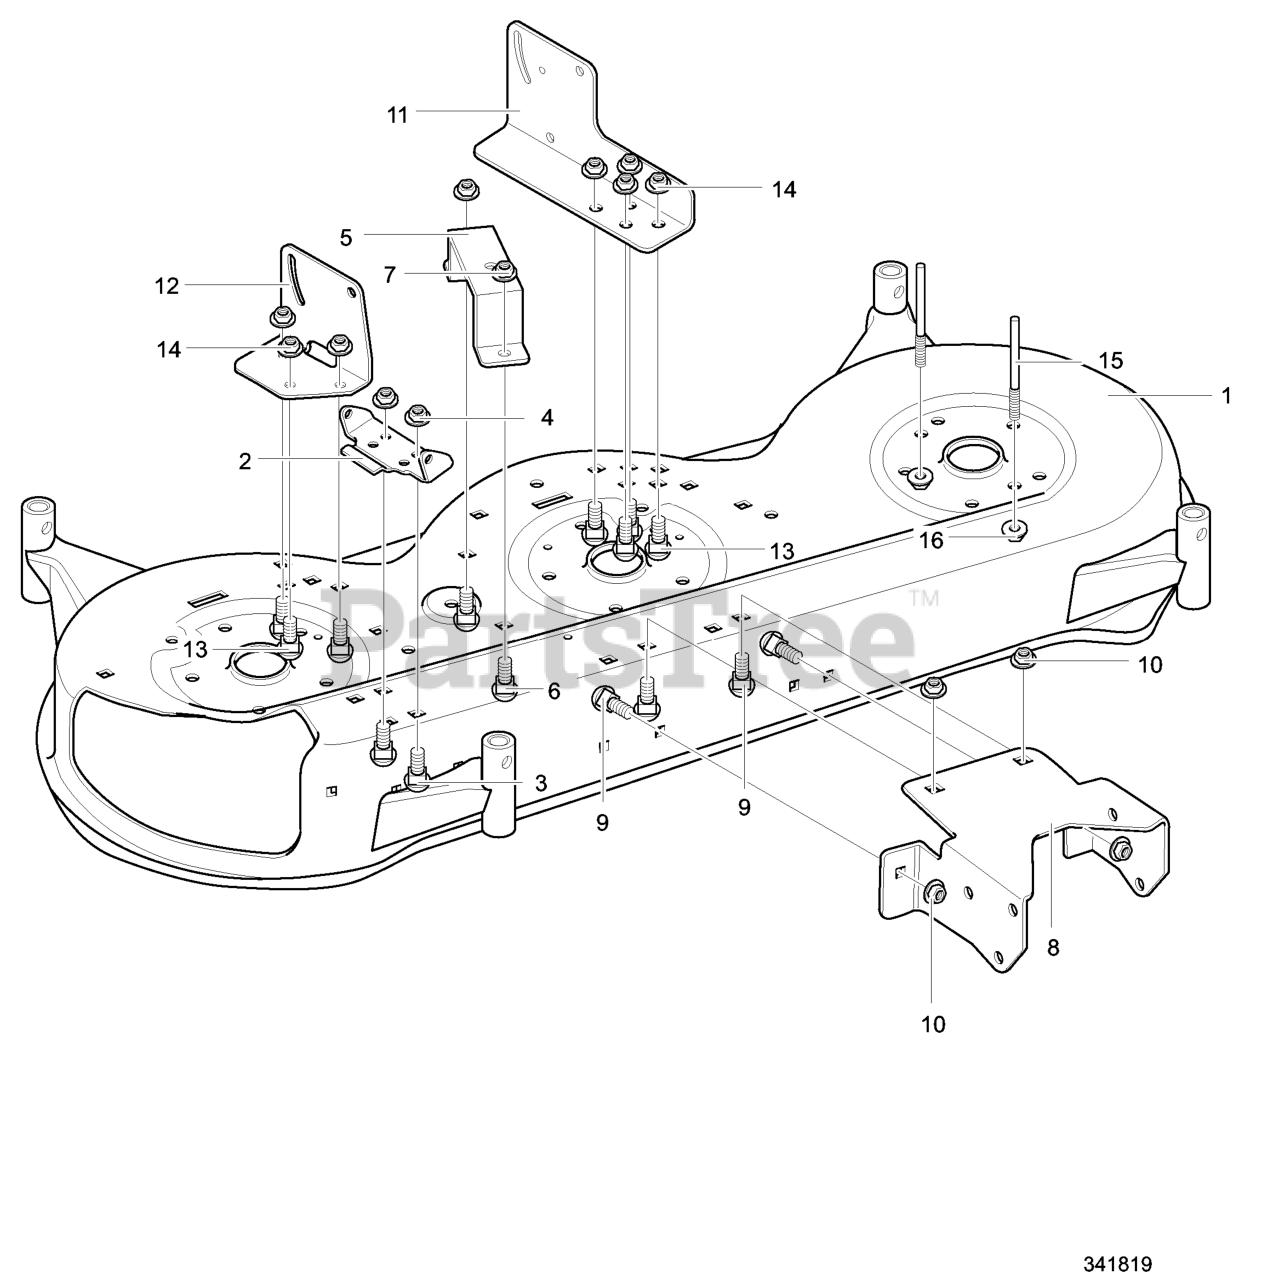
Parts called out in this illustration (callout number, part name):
1	MOWER DECK, 46"
2	HINGE, CHUTE BRACKET
3	BOLT, CARRIAGE
4	LOCKNUT, FLANGE
5	BRACKET, BELL CRANK
6	BOLT, CARRIAGE
7	LOCKNUT, FLANGE
8	BRACKET, FRONT DECK
9	BOLT, CARRIAGE
10	LOCKNUT, FLANGE
11	BRACKET, LEFT LIFTER
12	BRACKET, RIGHT REAR
13	BOLT, CARRIAGE
14	LOCKNUT FLANGE
15	SCREW, GUIDE
16	LOCKNUT, FLANGE
